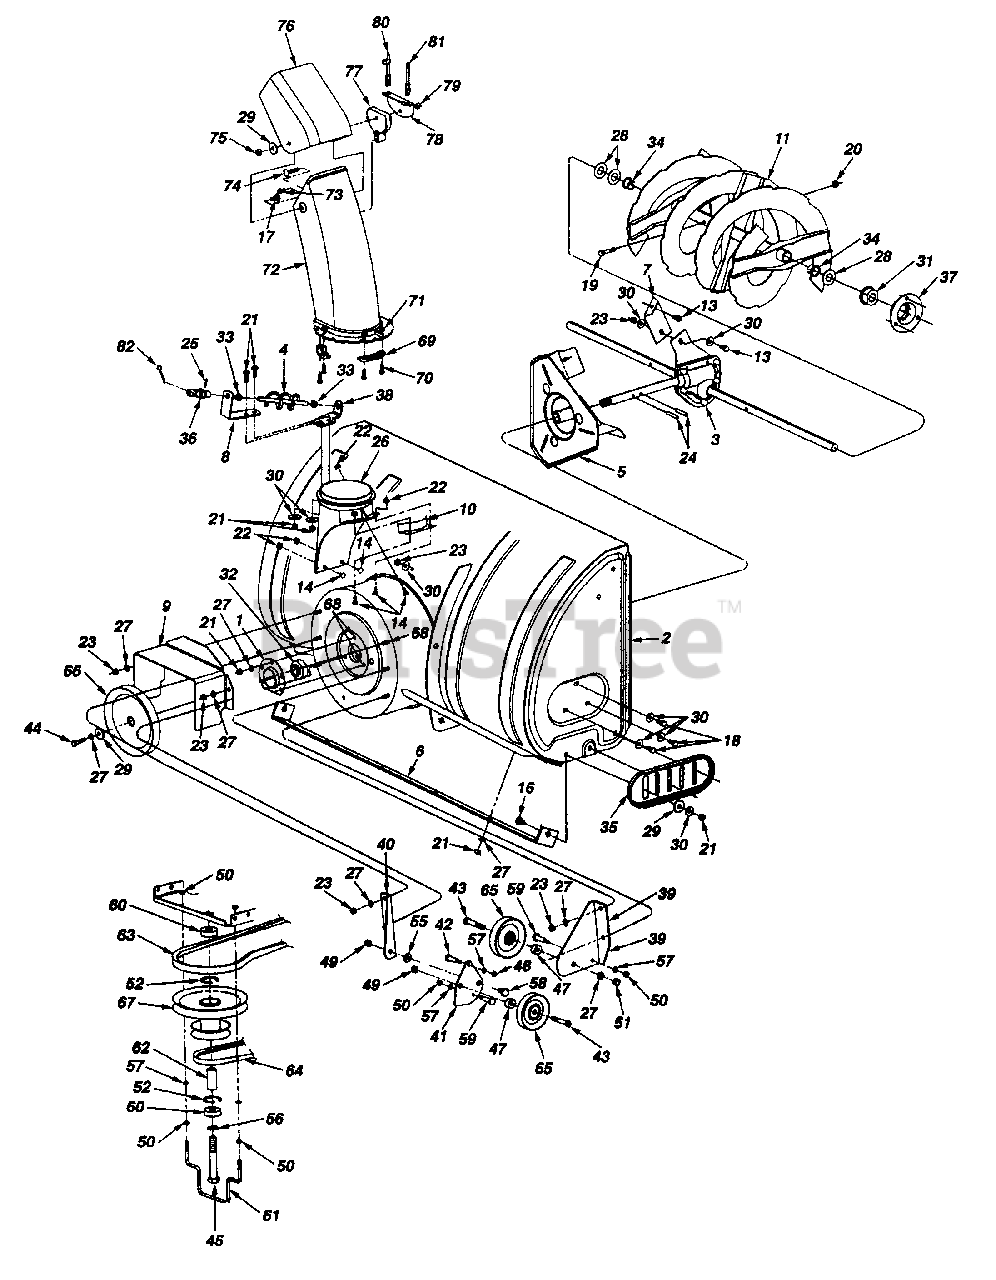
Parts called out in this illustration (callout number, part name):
1	Bearing Housing
4	Lower Chute Crank Ass'y.
14	Carriage Bolt 1/4-20 x .5" Lg.
16	Carriage Bolt 5/16-18 x 1" Lg.
17	Carriage Bolt 5/16-18 x .75" Lg.
18	Hex Wash. Hd. TT-Scr. 5/16-18 x .62" Lg.
19	Shear Bolt 5/16-18 x 1.5" Lg.
20	Hex L-Nut 5/16-18 Thd.
21	Hex Nut 5/16-18 Thd. (Gr. 5)
22	Hex Flange L-Nut 1/4-20 Thd.
23	Hex Nut 5/16-24 Thd. (Gr. 5)
24	Spring Pin 1.5" Lg.
25	Spiral Pin .818" Lg.
26	Chute Adapter
27	L-Wash. 5/16" I.D.
28	Fl-Wash. .76" I.D. x 1.49" O.D.
29	Fl-Wash. .344" I.D. x 1.125" O.D.
30	Bell-Wash. .345" I.D. x .88" O.D.
31	Hex Flange Bearing .75" I.D.
32	Flange Ball Bearing .75" I.D.
33	Plastic Bushing .38" I.D.
34	Flange Bushing .8" I.D.
36	Joint Block Ass'y.
43	Hex Bolt 3/8-16 x 1.75" Lg. (Gr. 5)
44	Hex Bolt 5/16-24 x 1.25" Lg. (Gr. 5)
45	Hex Bolt 5/8-18 x 4.25" Lg. (Gr. 5)
48	Hex Cent. L-Nut 1/4-20 Thd.
49	Flanged L-Nut 3/8-16 Thd.
50	Hex Nut 1/4-20 Thd. (Gr. 5)
51	Hex Nut 3/8-16 Thd. (Or. 5)
52	Snap Ring
55	Fl-Wash. .51" I.D. x 1" O.D.
56	Fl-Wash. 5/8" I.D. x 1" O.D.
57	L-Wash. 1/4" I.D.
58	Shld. Bolt .5" Dia. x .17" Lg.
59	Shld. Bolt .374" Dia. x 1.16" Lg.
60	Ball Bearing 5/8" I.D.
61	Belt Guard Rod
62	Spacer .635" I.D.
63	"V"-Belt
64	"V"-Belt
65	Idler Pulley
66	Auger Pulley
67	Double Pulley
68	Clinch Bolt 5/16-18 x .75" Lg.
69	Chute Flange Keeper
70	Hex Bolt 1/4-20 x .75" Lg.
71	Hex Flanged L-Nut 1/4-20 Thd.
72	Lower Chute
73	Hex Wash. Hd. AB-Tap Scr. 1/4" x 5/8" Lg.
74	Carriage Bolt 5/16-18 x 1.5" Lg.
75	Hex Jam L-Nut 5/16-18 Thd.
76	Upper Chute
77	Cable Guide
79	Hex L-Nut 5/16-18 Thd.
80	Chute Control Cable w/Clip
81	Chute Control Cable
82	Cotter Pin .75" Lg.
